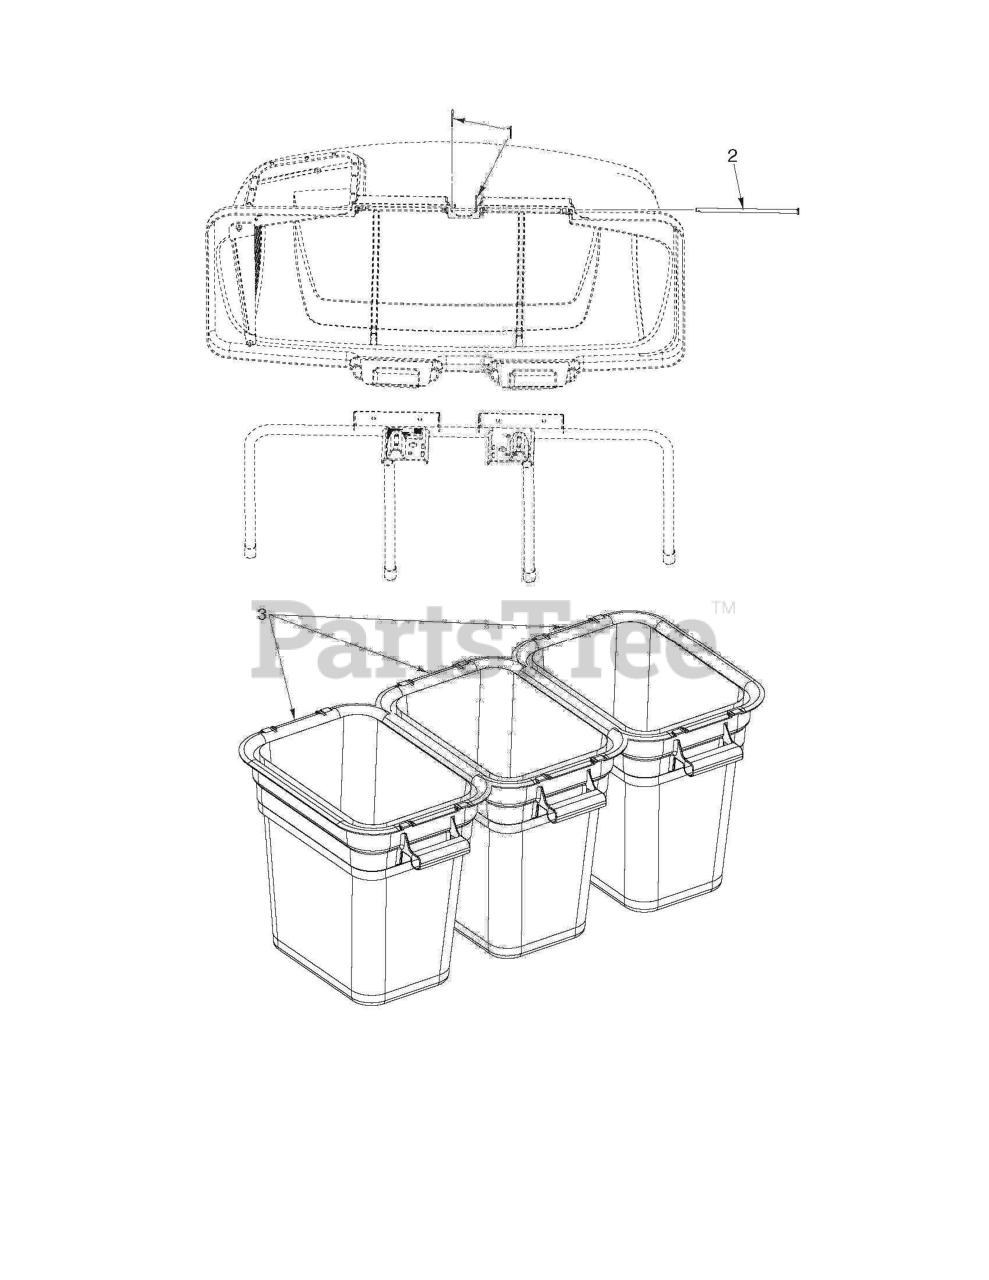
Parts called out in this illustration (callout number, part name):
1	Pins
2	BAGGER.HINGE.PIN
3	CONTAINER BAG, SOFT
